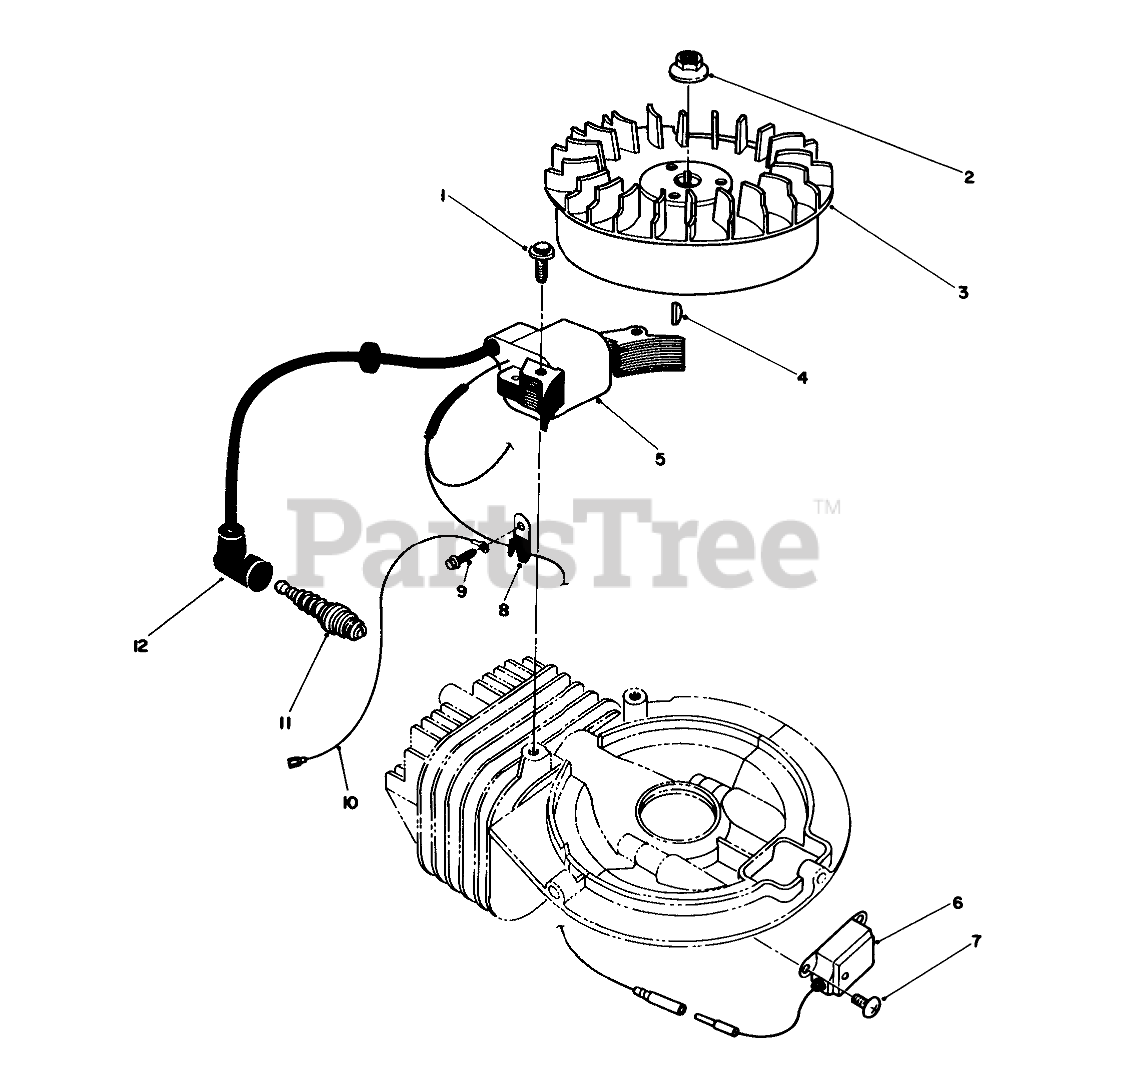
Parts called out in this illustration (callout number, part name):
1	SCREW
3	FLYWHEEL
5	MAGNETO COIL
6	MAGNETO MODULE
7	SCREW
8	CLAMP
11	Sparkplug
12	CAP-SPARKPLUG
